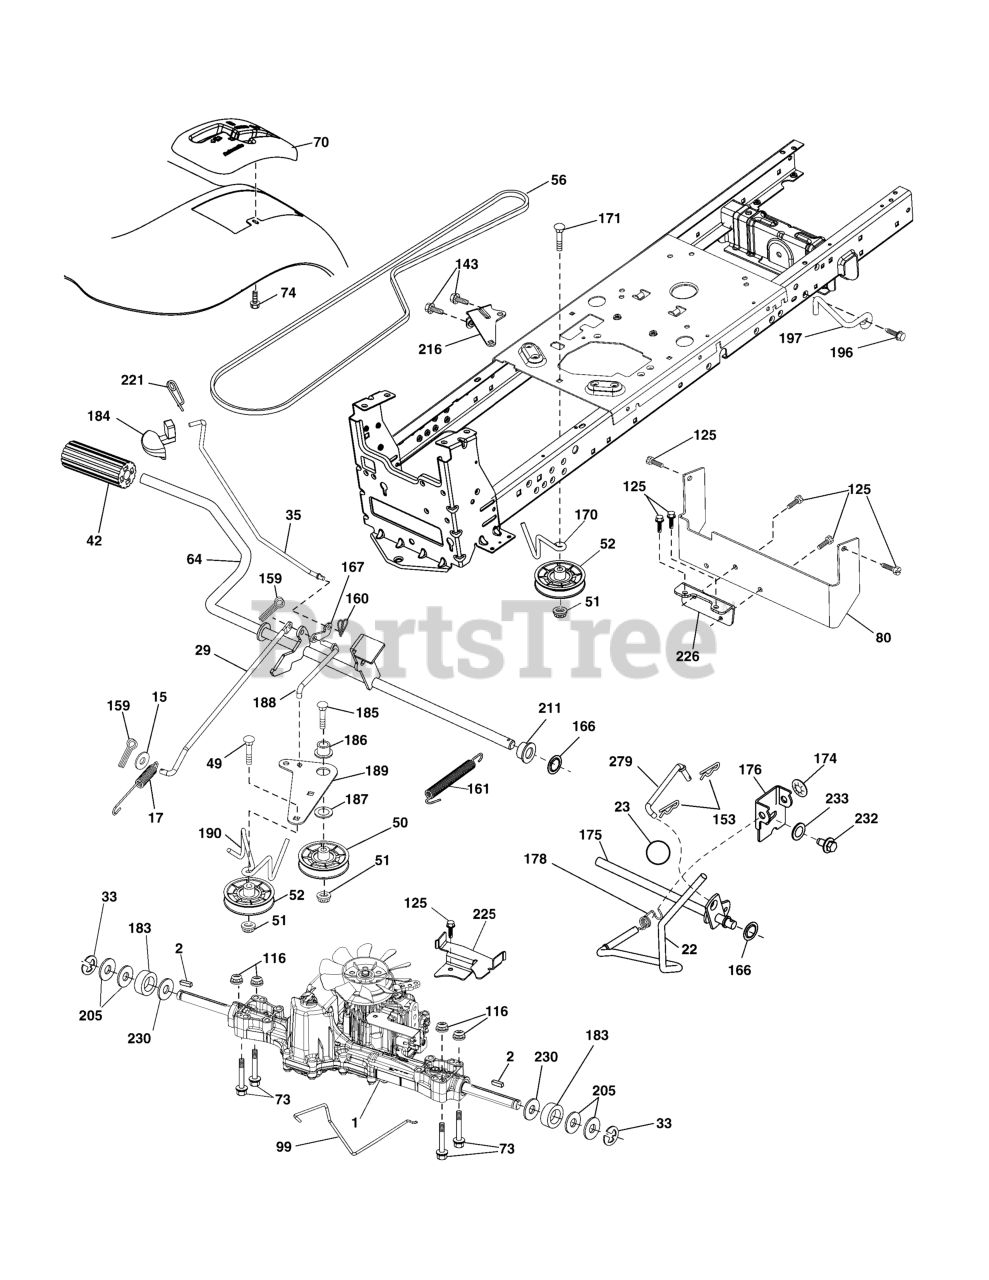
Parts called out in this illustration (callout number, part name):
1	Transaxle, TUFFTORQ K46 BA
2	Key Square
15	Washer 13/32 x 13/16 x 16 Ga.
17	Spring, Brake
22	Rod Shift
23	Knob Deluxe 1/2-13 unc
29	Rod, Brake
33	Ring E
35	Rod, Brake, Park
42	Cover, Foot Pedal
49	Bolt
50	Pulley Idler Flat
51	Lock Nut 3/8-16
52	Idler V-Groove 910" Offset
56	V-Belt, Drive
64	Shaft Asm. Pedal Brake Control
70	Console Shift
73	Bolt 5/16-18 Gr. 5
74	Screw Hex Wsh Hi-Lo 1/4 x 1/2 unc
80	Strap Torque
99	Rod Bypass
116	Nut Lock Hex Flange 5/16-18
125	Screw 5/16-18 x 3/4
143	Screw
153	Retainer Spring
159	Pin Cotter 1/8 x 3/4
160	Retainer Clip
161	Spring, Return, Clutch
166	Nut Push .625
167	Latch Brake Parking
170	Keeper Belt Centerspan
171	Bolt RDHD 3/8-16 unc x 2
174	Nut Push
175	Shaft Asm Shift
176	Arm Clevis Rod Shift
178	Spring Shift
183	Spacer Split
184	Handle Parking Brake
185	Bolt Rdhd Sqnk 3/8-16 x 2-3/4 Gr.
186	Spacer Retainer
187	Washer
188	Link Clutch Ground Drive
189	Bellcrank Ground Drive
190	Keeper Bellcrank Ground Drive
196	Screw 3/8-16 x 1
197	Link Clutch Anti-Rotation
205	Washer
211	Bearing Shaft Brake
216	Bracket Pulley
221	Retainer Spring Clip Handle
225	Keeper Belt Trans.
226	Bracket Mount Torque
230	Washer Harden
232	Bolt Fin Hex 7/16-14 x 1 Gr. 5
233	Washer Serrated
279	Link Shift T/A
